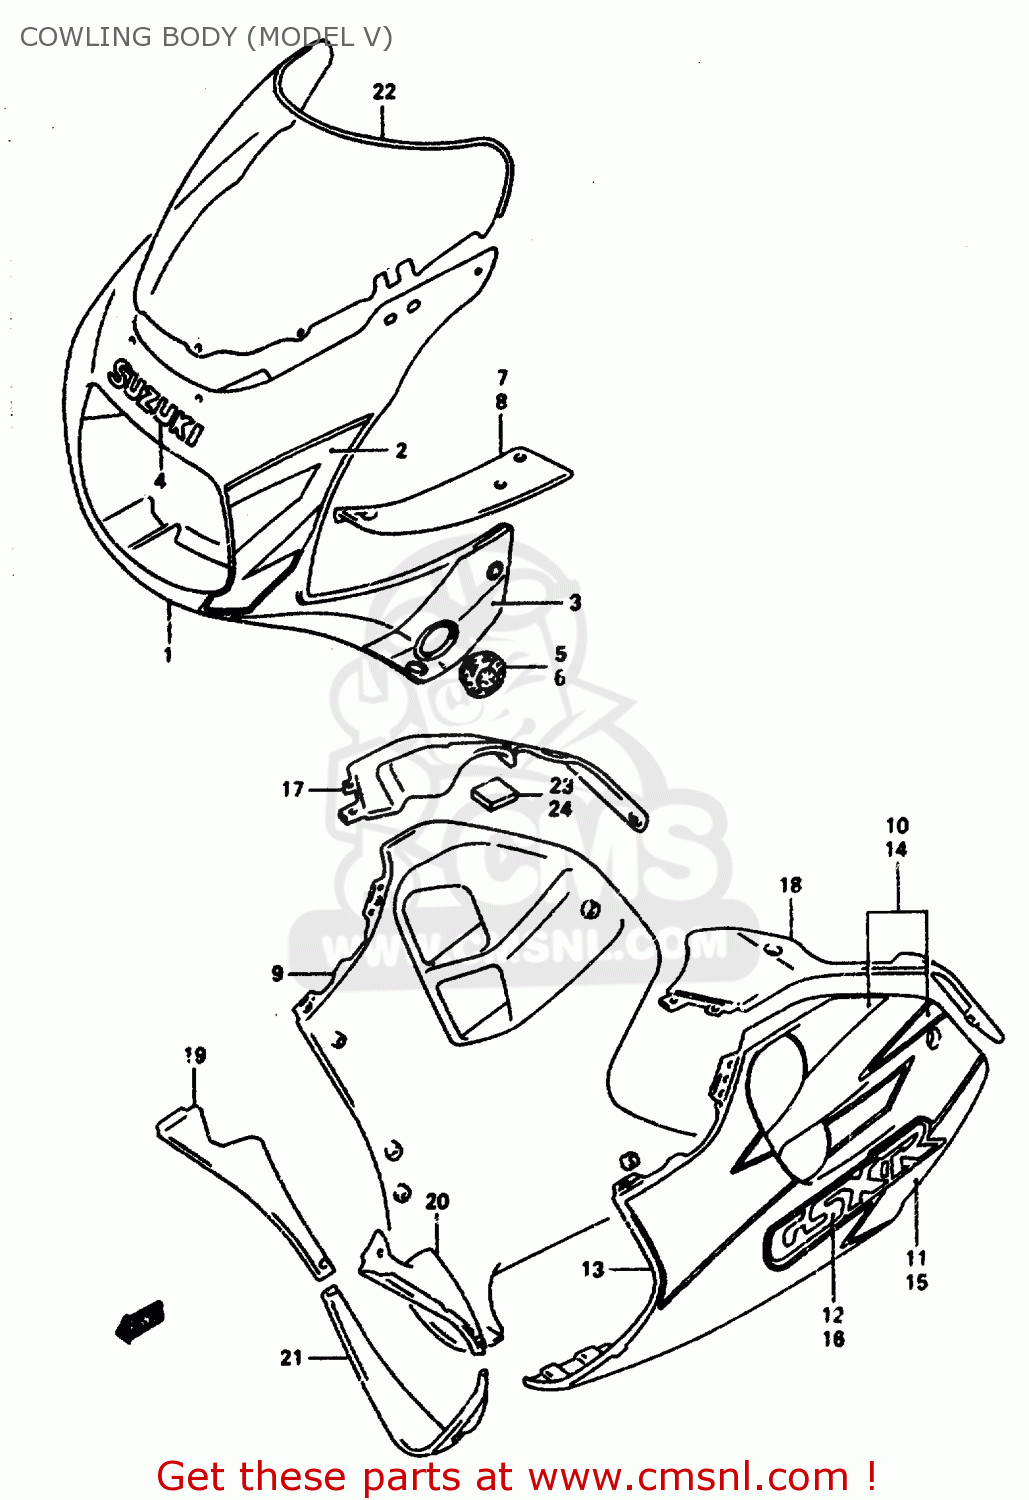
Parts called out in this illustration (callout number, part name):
1	COWLING ASSY,BODY
2	TAPE SET,BODY COWL FR
3	TAPE SET,BODY COWLING SIDE
4	EMBLEM,BODY COWL
5	PLATE,TURN SIGNAL,RIGHT
6	PLATE,TURNSIGNAL LAMP,L
7	PANEL,COWLING UPR,R
8	PANEL,COWLING UPR,L
9	COWLING ASSY,UNDER,R
10	TAPE,COWL UNDER,R
11	TAPE SET,COWL UNDER,R
12	EMBLEM,COWLING UNDER
13	COWLING ASSY,UNDER,L
14	TAPE,COWL UNDER,L
15	TAPE SET,COWL UNDER,L
16	EMBLEM,COWLING UNDER
17	PANEL,LWR,R
18	PANEL,LWR,L
19	COWLING,UNDER INNER,R
20	CUSHION,CHAIN CASE
21	COWLING,UNDER CTR
22	SCREEN SET,WINDOW
23	CUSHION,UNDER COWLING
24	CUSHION,CHAIN CASE
